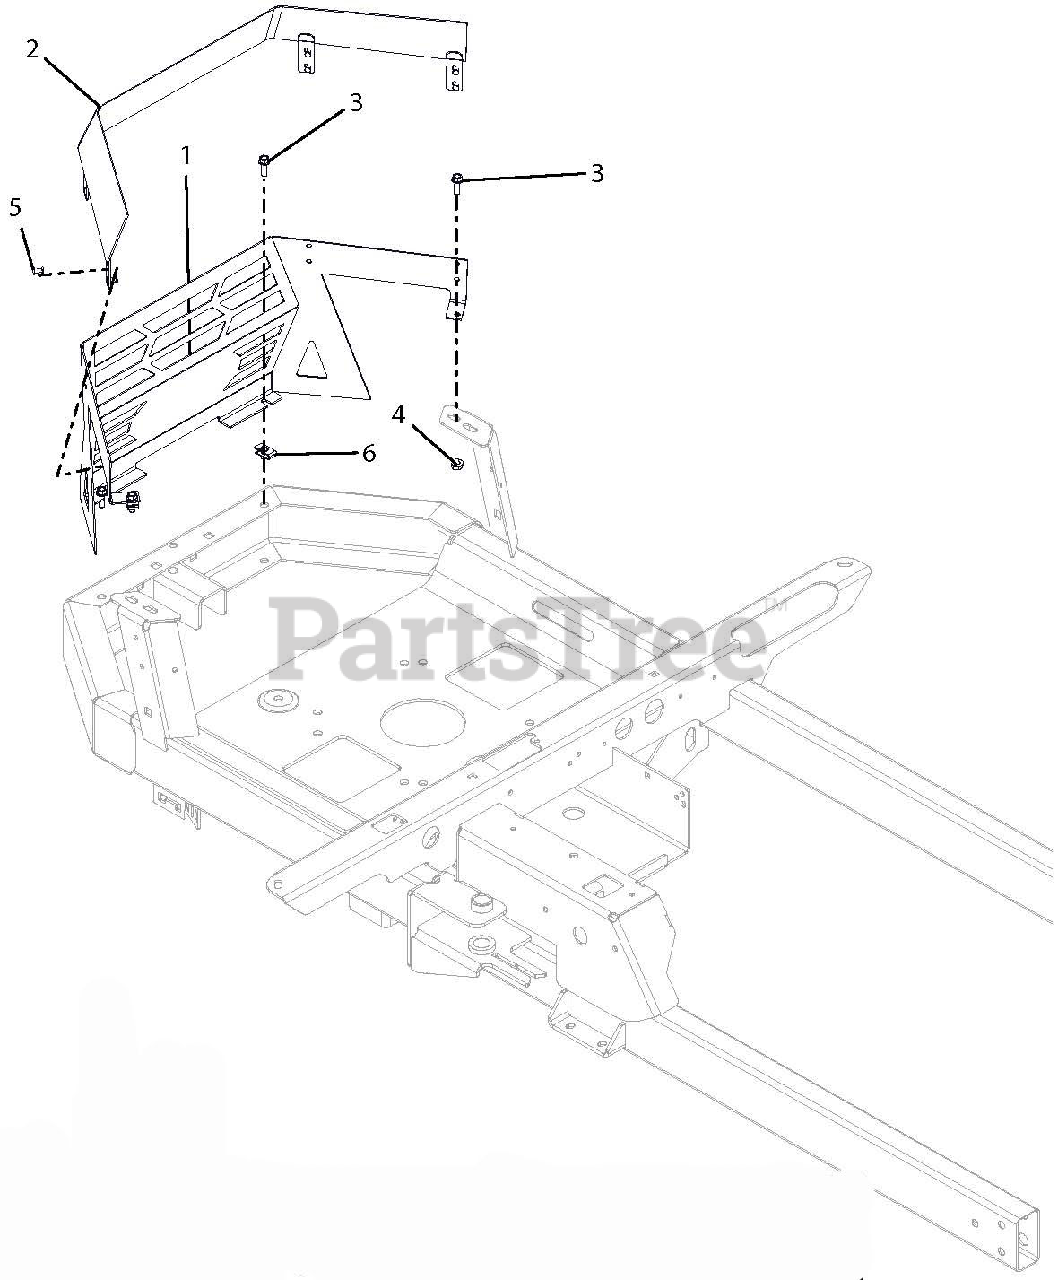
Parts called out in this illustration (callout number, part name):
1	SHROUD, ENGINE (REAR)
2	BRACKET, ENGINE SHROUD TRIM
3	BLT-HEX .25-20X.75 HWH YZ GR5
4	@NUT-LK-TOP-FLG .25-20 YWZC
5	RIVET, #66 STEEL POP PD BLACK
6	NUT-RTNR .25-20X.56
